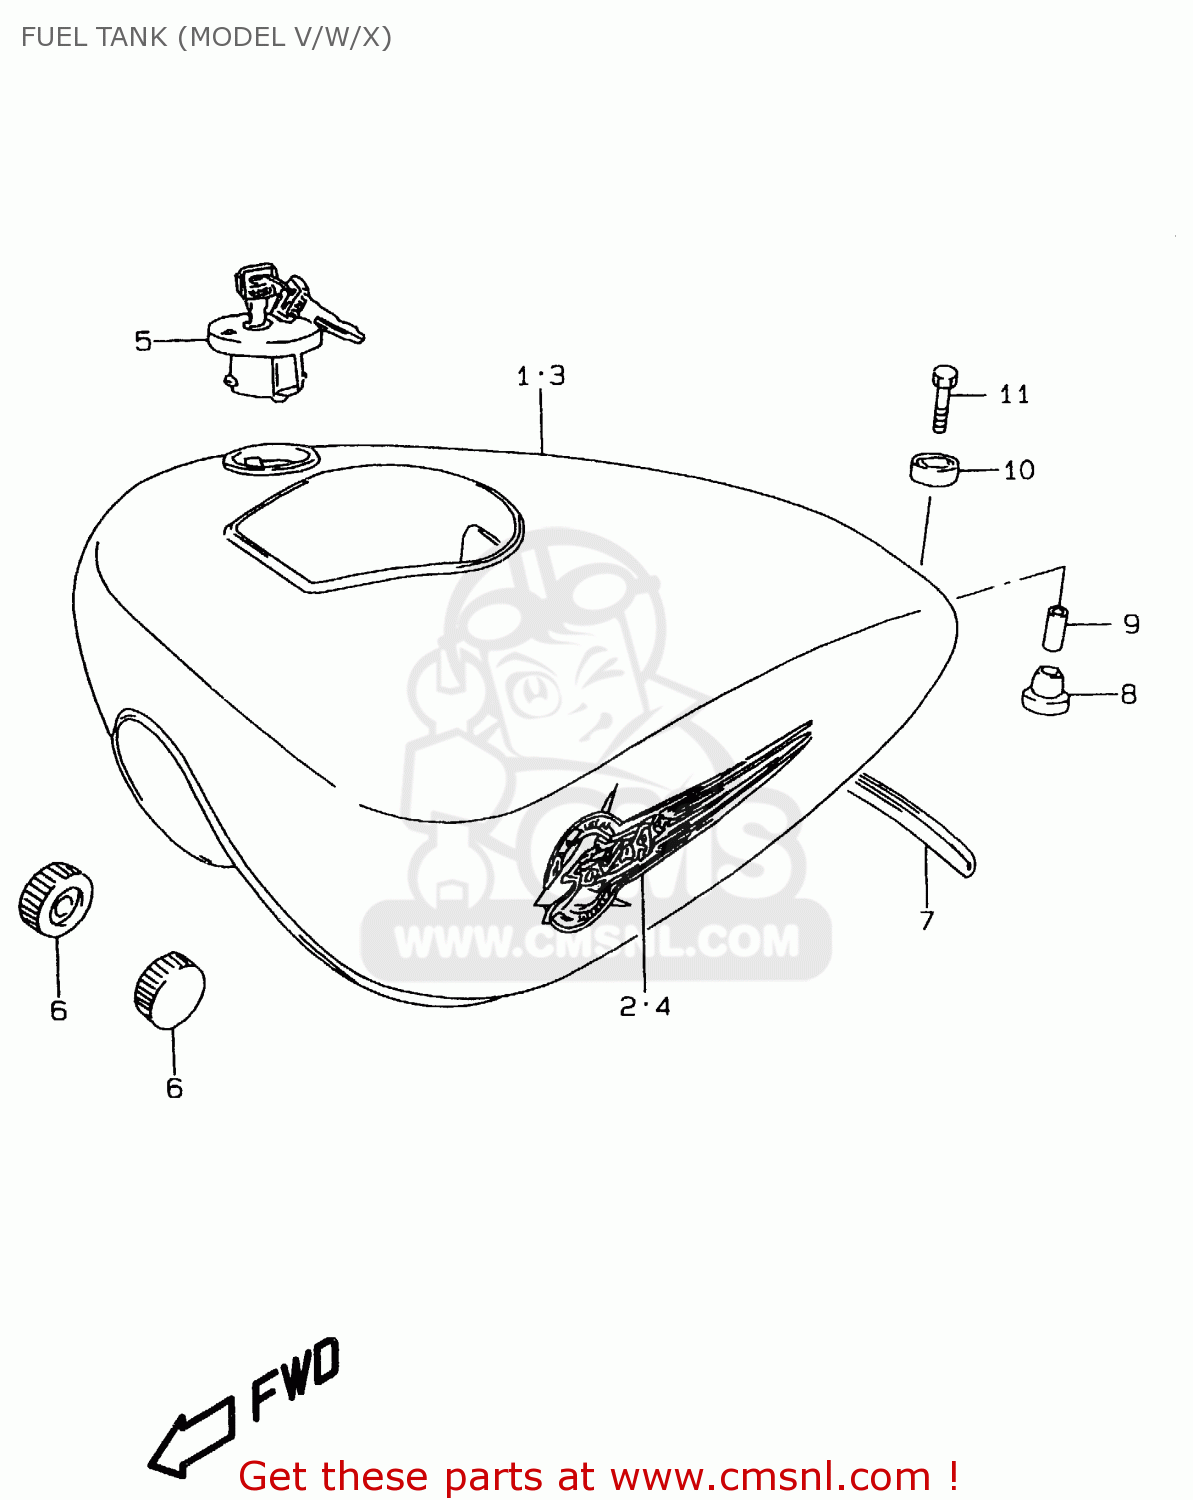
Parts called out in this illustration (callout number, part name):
1	TANK ASSEMBLY,FUEL
2	TAPE SET,FUEL TANK
3	TANK ASSY,FUEL
4	TAPE SET,FUEL TANK
5	CAP SET,FUEL TANK
6	CUSHION
7	MOLDING,FUEL TANK RR
8	CUSHION
9	SPACER(6.5X9X18)
10	CUSHION
11	BOLT
